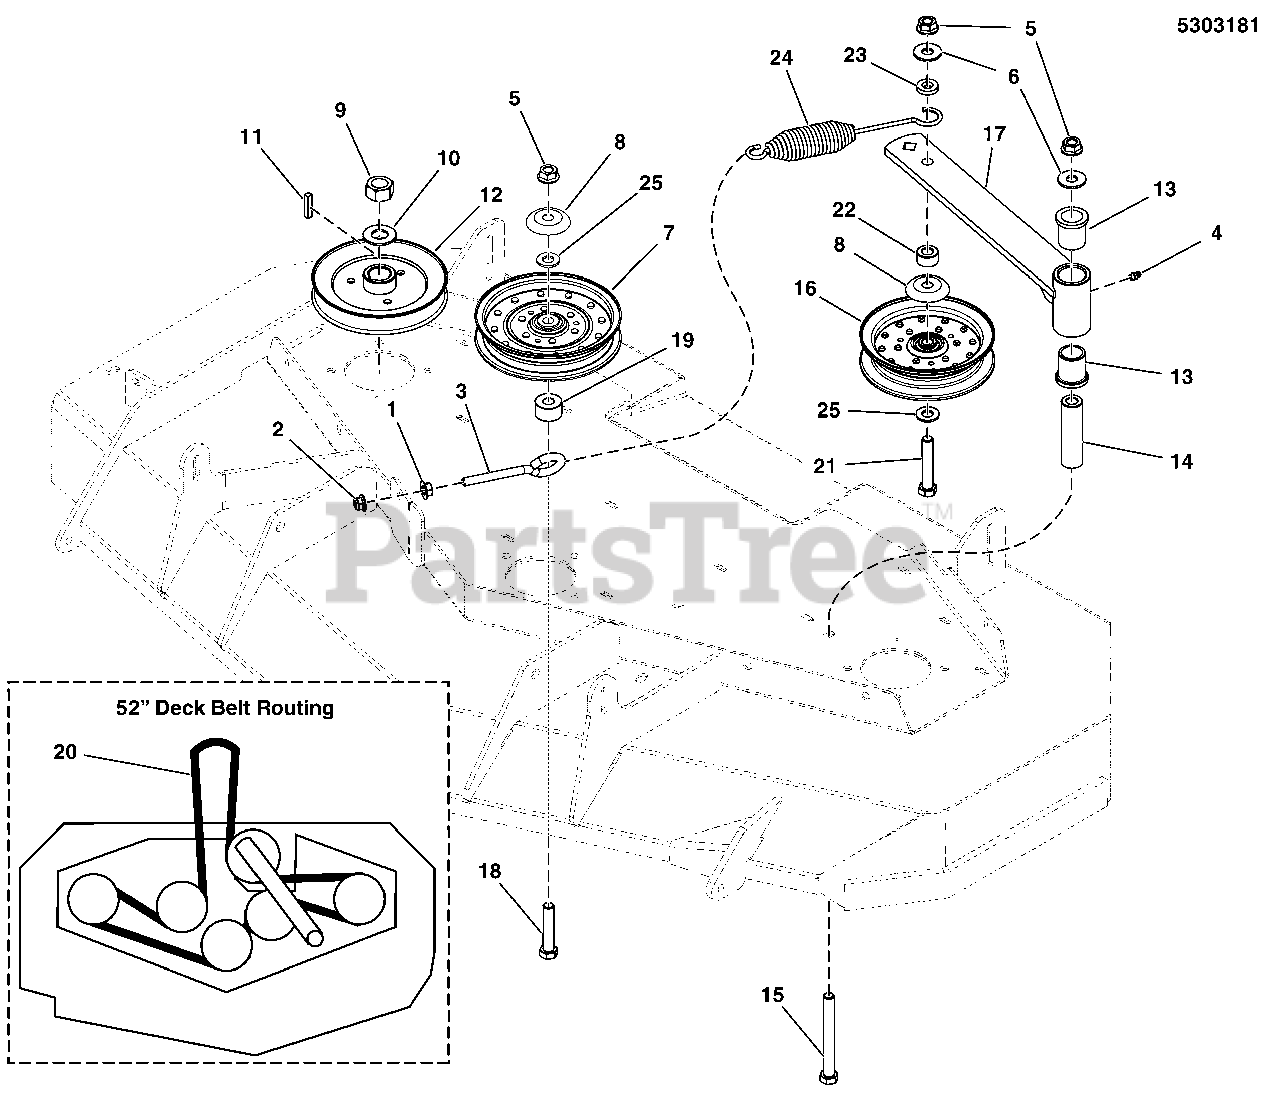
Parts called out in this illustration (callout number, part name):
1	NUT, 3/8-16 HEX SERRATED FLANGE
2	NUT, 3/8-16 HEX NYLOCK FLANGE
3	EYE BOLT, 3/8-16 X 6, 3.0 THREAD
4	GREASE FITTING, 1/4-28 STRAIGHT
5	NUT, 1/2-13 HEX NYLOCK FLANGE
6	WASHER, 1/2 USS
7	*PULLEY, FLAT IDLER, 6-3/4"
8	SHIELD, PULLEY BEARING
9	NUT, 3/4-16 HEX
10	WASHER, 3/4 BELLEVILLE
11	KEY, 1/4 SQ X 1-1/4
12	PULLEY, 5.926 OVER BALL
13	BUSHING, FLANGE
14	SPACER, .52 X 1.00 X 3.50
15	BOLT, 1/2-13 X 4-1/2 GD5 YZ
17	WELD, IDLER ARM - 52" - BLK
18	BOLT, 1/2-13 X 2-1/2 GD5 YZ
19	SPACER, .52 X 1.25 X .70, CZ
20	BELT, 5V SEC, 162.4" EL, ARAMID, WRPD, RC
21	BOLT, 1/2-13 X 2-3/4 GD5 YZ
22	SPACER, .52 X 1.00 X .56, CZ
23	SPACER, .52 X 1.00 X .22, CZ
24	SPRING, EXTENSION, SWIVEL. LONG HOOK
25	WASHER, 1/2 SAE
